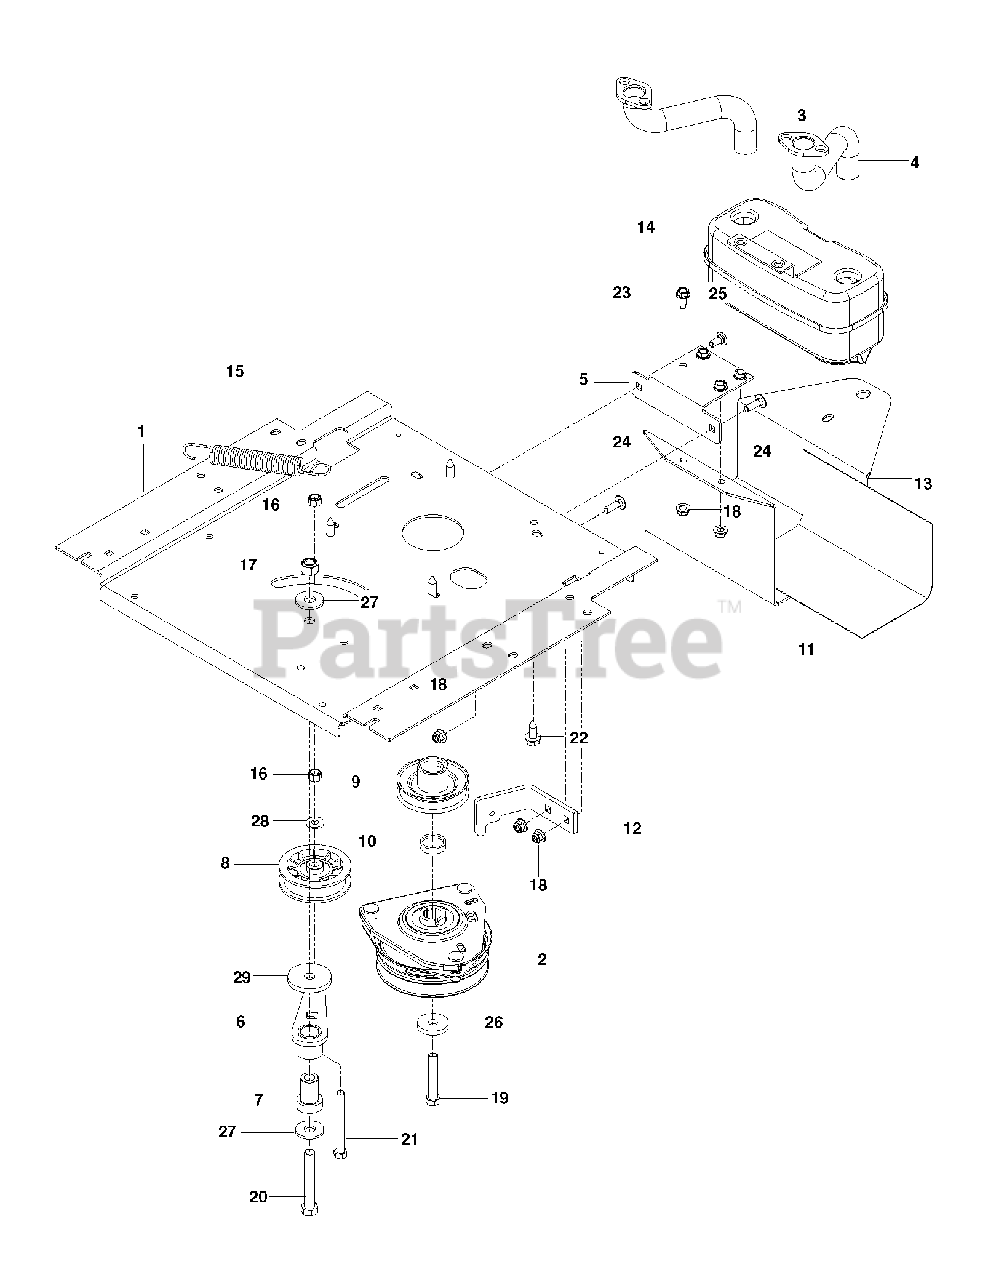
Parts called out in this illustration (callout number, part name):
1	PLATE, ENGINE BLK
2	CLUTCH.ELECTRIC.LT.48"*
3	RP.EXHAUST.TUBE.LH.BS/TWIN
4	EXHAUST.TUBE.RH.BS/TWIN
5	BRACKET, MUFFLER, BLACK
6	IDLER ARM WELDMENT
7	IDLER SPINDLE
8	PULLEY, IDLER RAKE & ZTR
9	RP PULLEY, ENGINE
10	SPACER, HUB PULLEY
11	GUARD, MUFFLER, BLACK
12	CLUTCH STOP OGR BLK
13	GUARD, MUFFLER, BLACK
14	MUFFLER ASM TWIN
15	SPRING, DECK DRIVE
16	NUT
17	NUT.LK.W/WSH.1/2.
18	5/16-18 NYLOC FLANGE NUT
19	HCS 7/16-20 X 2.5 GR8
20	HCS 1/2-13 X 3-1/4 GD 5 ZD
21	HCS 3/8-16X3-1/2 TAPBLT GR5 ZD
22	HHFS 3/8-16 X 1.0 THD FORMING
23	SCREW
25	BOLT 5/16-18 X3/4 ZN/YEL GR 5
27	WASHER.9/16 X 1 3/8 X 12 GA.
28	WASHER
29	HEAVY WASHER
